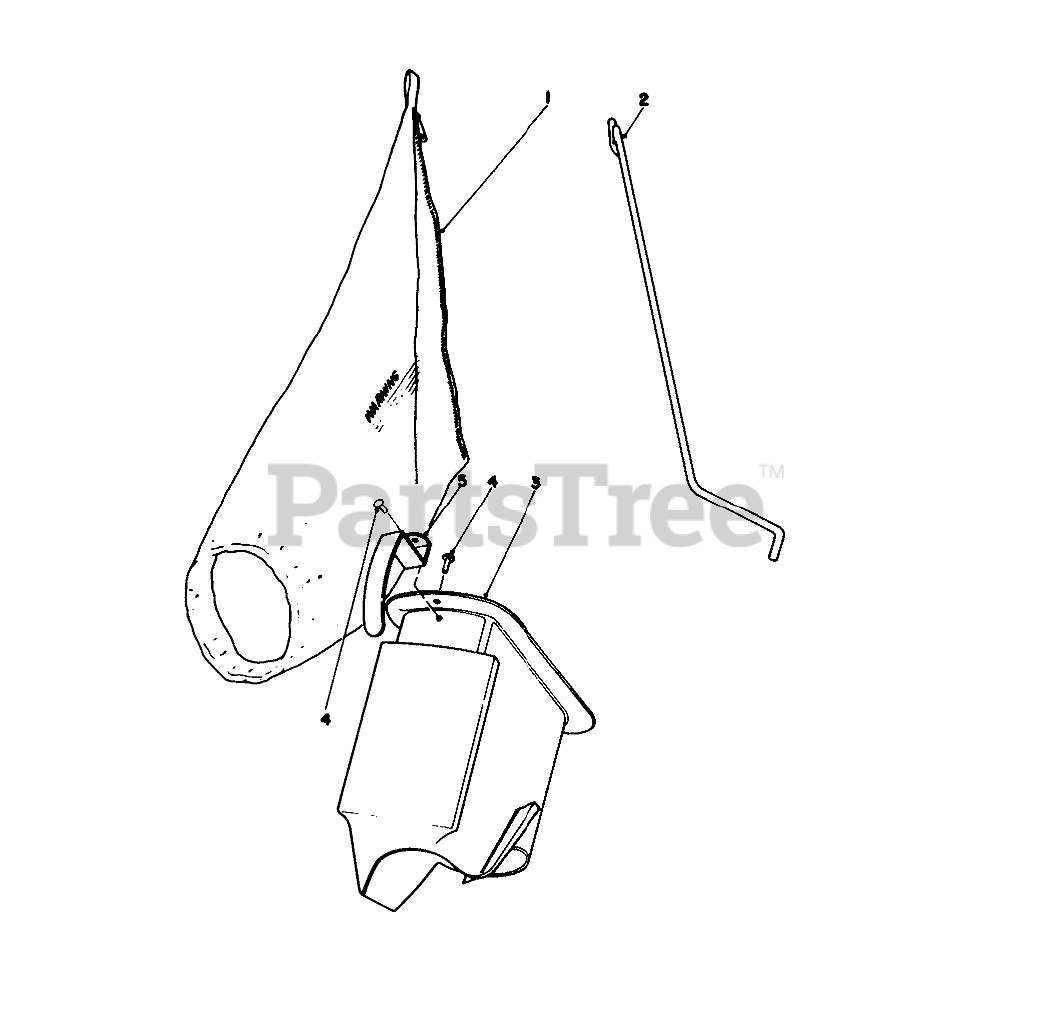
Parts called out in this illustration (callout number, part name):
1	BAG REPLACMNT44-0540
2	Bag Rod
3	Grass Chute (Incl. Ref. #4 & 5)
4	RIVET 3/16 X 7/16
5	HANDLE-GRASS CHUTE
